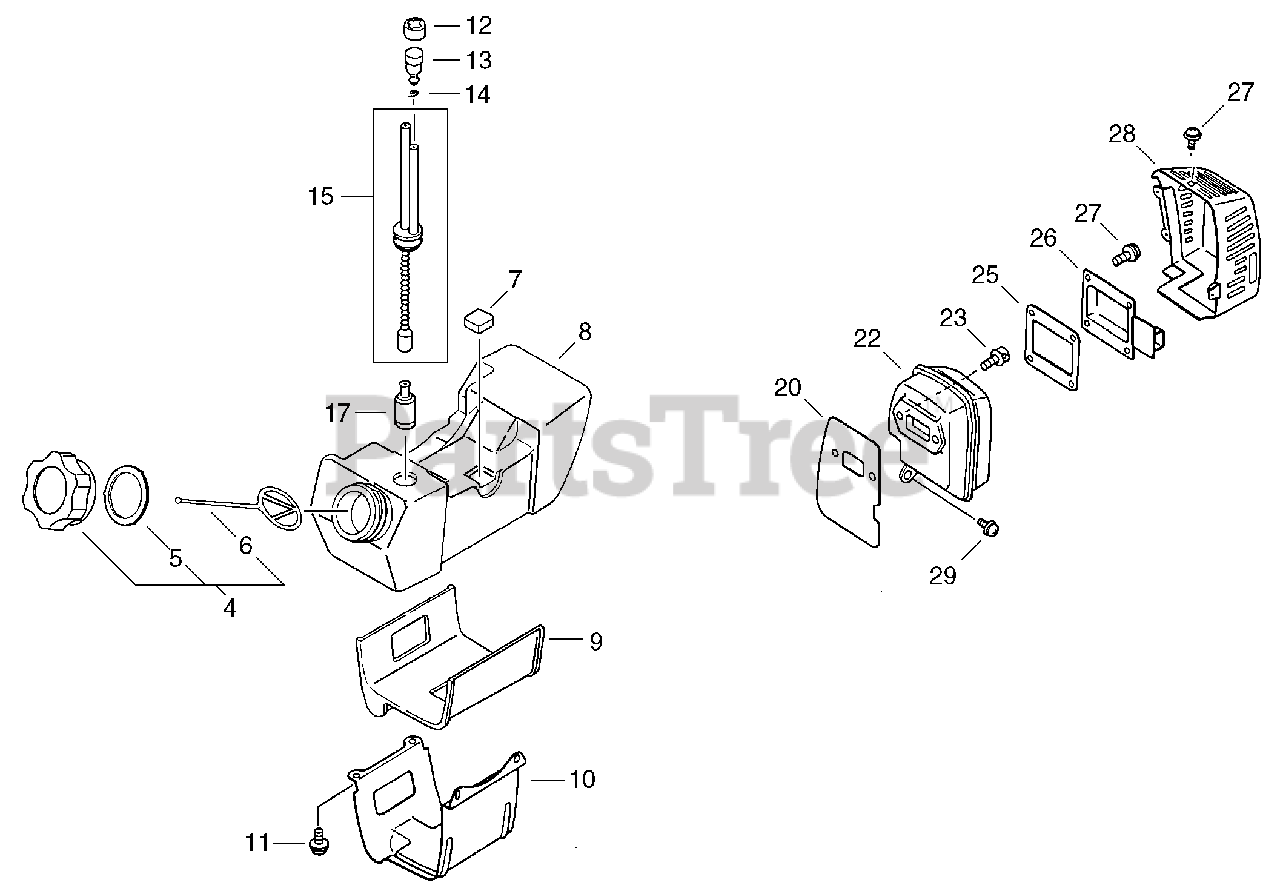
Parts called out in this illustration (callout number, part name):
4	CAP ASSY - ORANGE
5	GASKET, CAP
6	CONNECTOR, CAP
8	TANK, FUEL
10	BRACKET, FUEL TANK
11	SCREW - 5X14
12	COVER, VENT
13	VENT, FUEL TANK
14	CLIP - 6.5
15	FUEL PIPE ASSY
17	FILTER, FUEL
20	GASKET, EXHAUST
23	SCREW - 5X20
25	GASKET, EXHAUST
26	GUIDE, EXHAUST
27	SCREW - 4X10
28	COVER, EXHAUST
29	SCREW - 5X14
